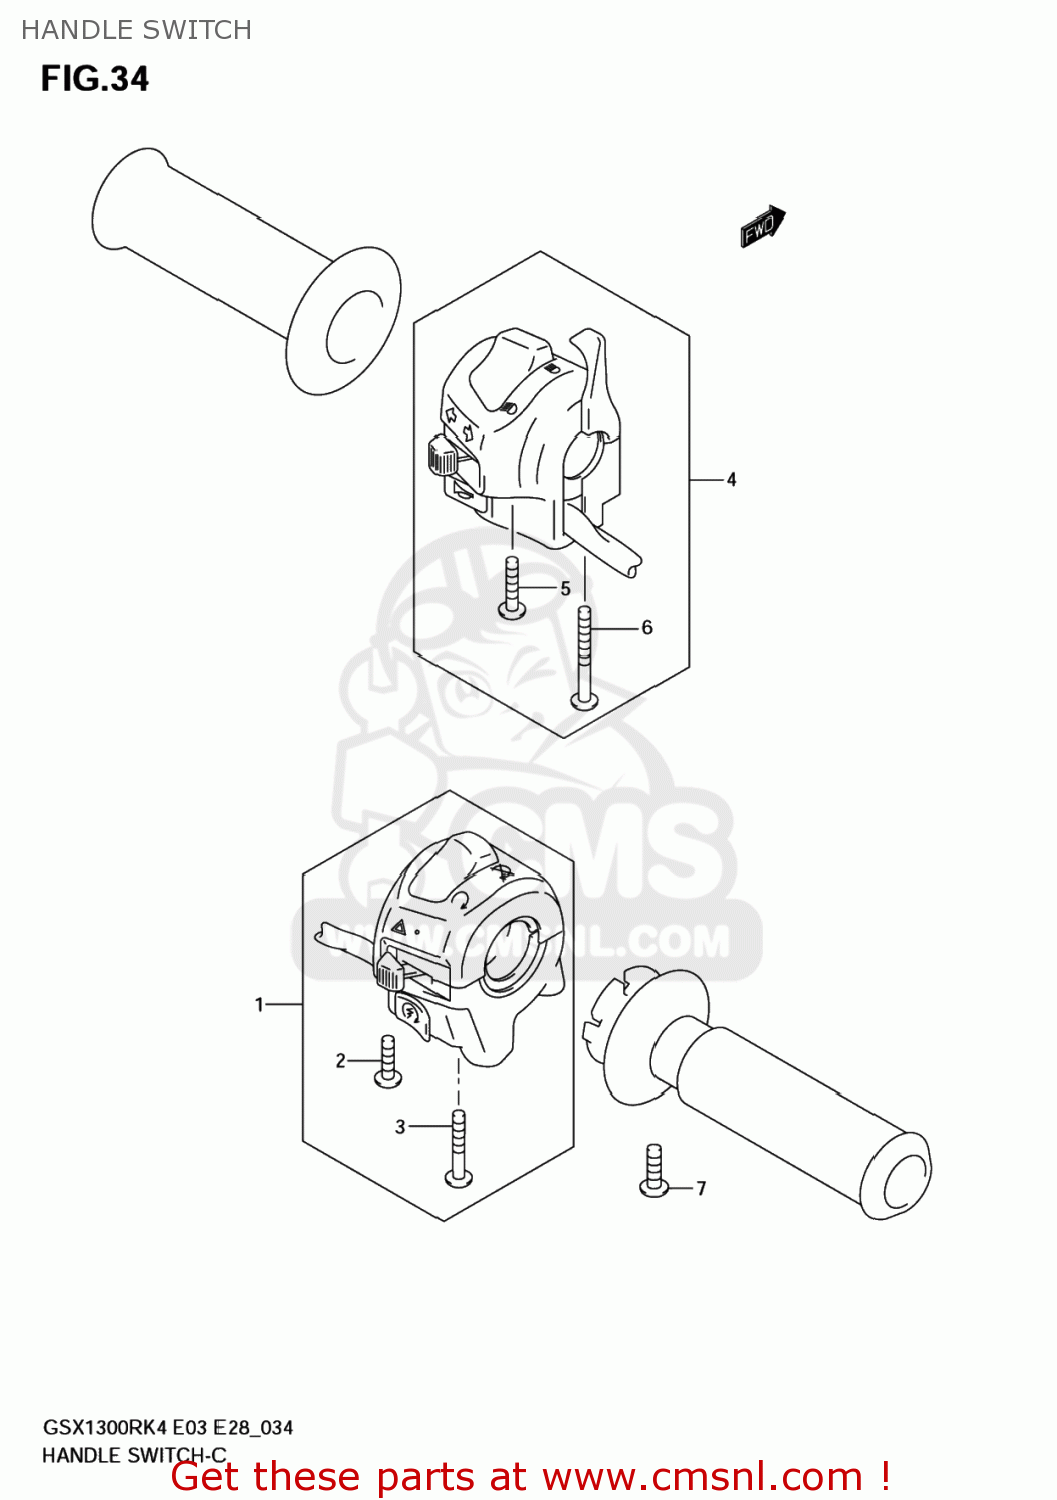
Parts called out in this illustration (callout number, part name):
1	SWITCH ASSY,HANDLE,R
2	SCREW
3	SCREW
4	SWITCH ASSY,HANDLE,L
5	SCREW
6	SCREW, 5X45
7	SCREW
